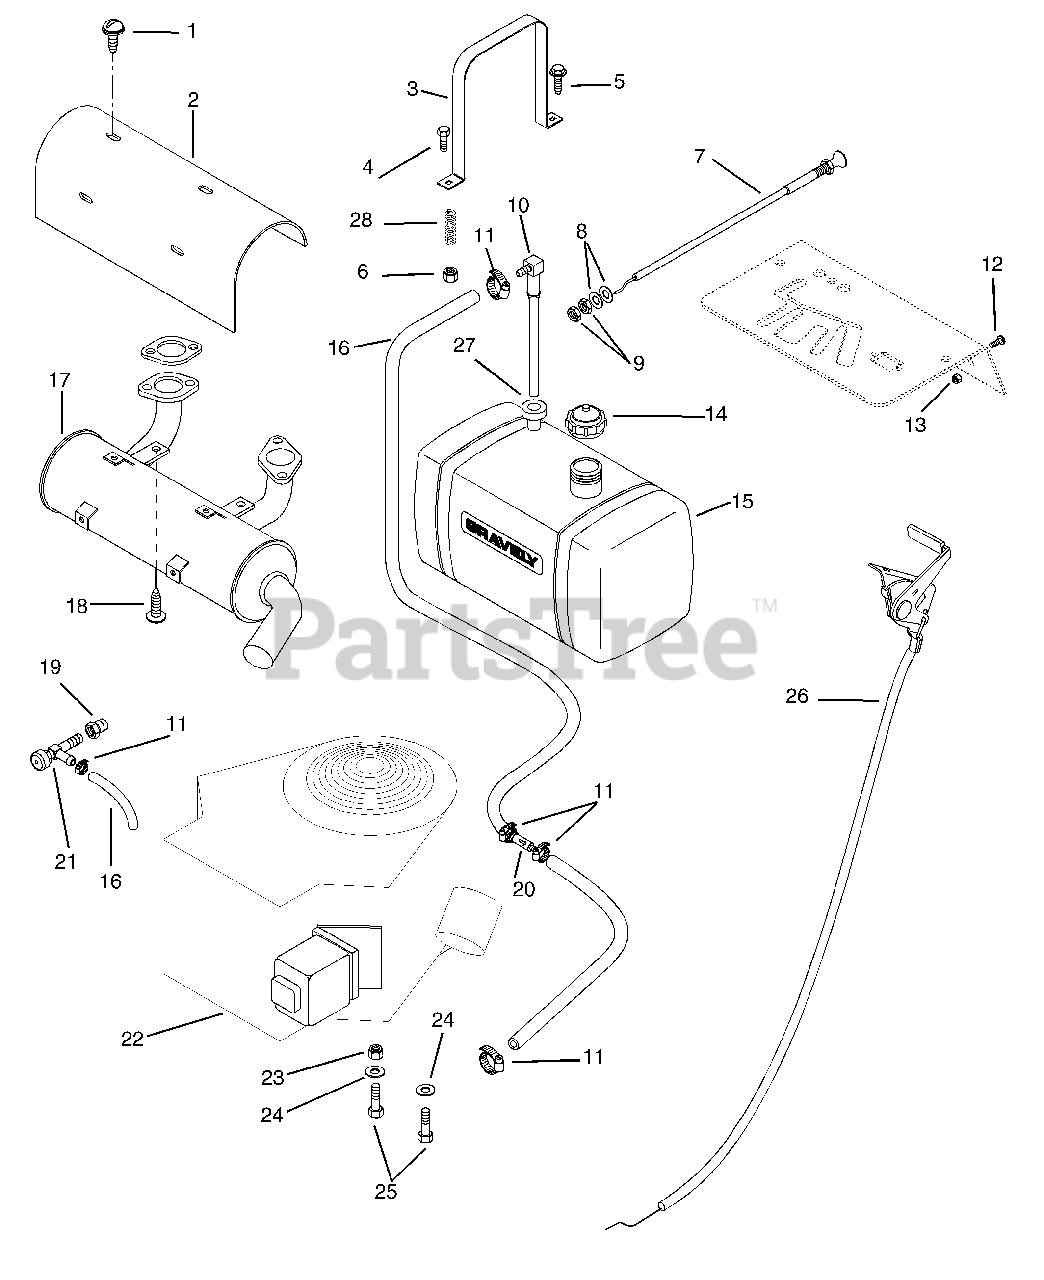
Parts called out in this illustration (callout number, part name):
1	Screw-Tap with Washer
2	Heat Shield
3	Strap-Fuel Tank
4	Bolt-Hex .25-20 x 1.75 Grade 5
5	Bolt-Hex .25-20 x .50 Grade 5
6	Nut-Locking-Center .25-20
7	Control-Choke
8	Washer-Flat-Steel .406 x .812 x .065
9	Nut-Jam .375-24
10	Fitting-Tank
11	Clamp-Hose Wire .490 x .510 x .116
12	Screw-Machine 10-32 x .50
13	Nut-Locking-Nylon 10-24 with Insert
14	Cap-Fuel Tank
15	Tank-Fuel
16	Gas Line-Bulk 1/4" I.D.
18	Screw-Tap 6-1 x 25
19	Adapter-Oil Drain
20	Filter-Fuel
21	Cock-Oil Drain
22	Engine-Robin 18HP
23	Nut-Locking-Center .31-18
24	Washer-Flat-Steel .344 x .688 x .065
25	Bolt-Hex .31-18 x 1.75 Grade 5
26	Cable-Control
27	Bushing
28	Spring-Compression .125 x .78 x 1.00
